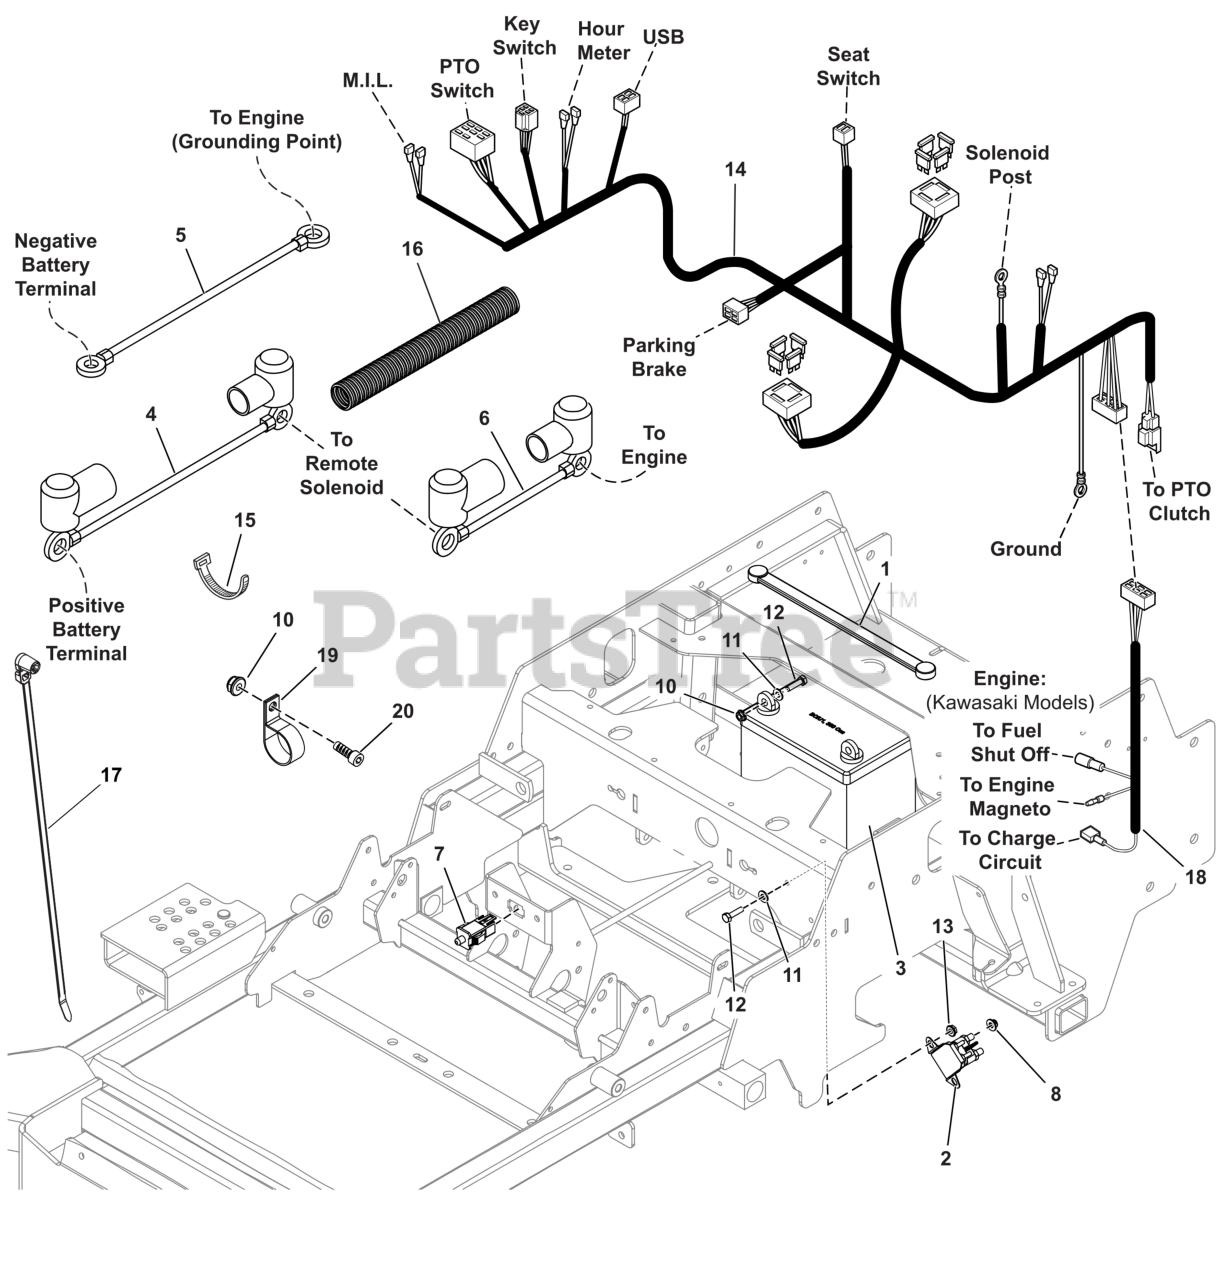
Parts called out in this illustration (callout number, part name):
1	STRAP, Rubber, 13"
2	SOLENOID
3	BATTERY, 11U1L, 350 CCA
4	BATTERY CABLE, POSITI
5	BATTERY CABLE
6	BATTERY CABLE
7	SWITCH, DP NO/NC SNAP
8	NUT, HEX KEPS, 1/4-20
11	WASHER
12	BOLT, 1/4-20 X 3/4" G
14	HARNESS, Wiring
15	TIE, Cable 11" Long
16	WIRE LOOM, 3/8 ID X 18 IN
17	CABLE, Tie (Sold as a bag of 5)
